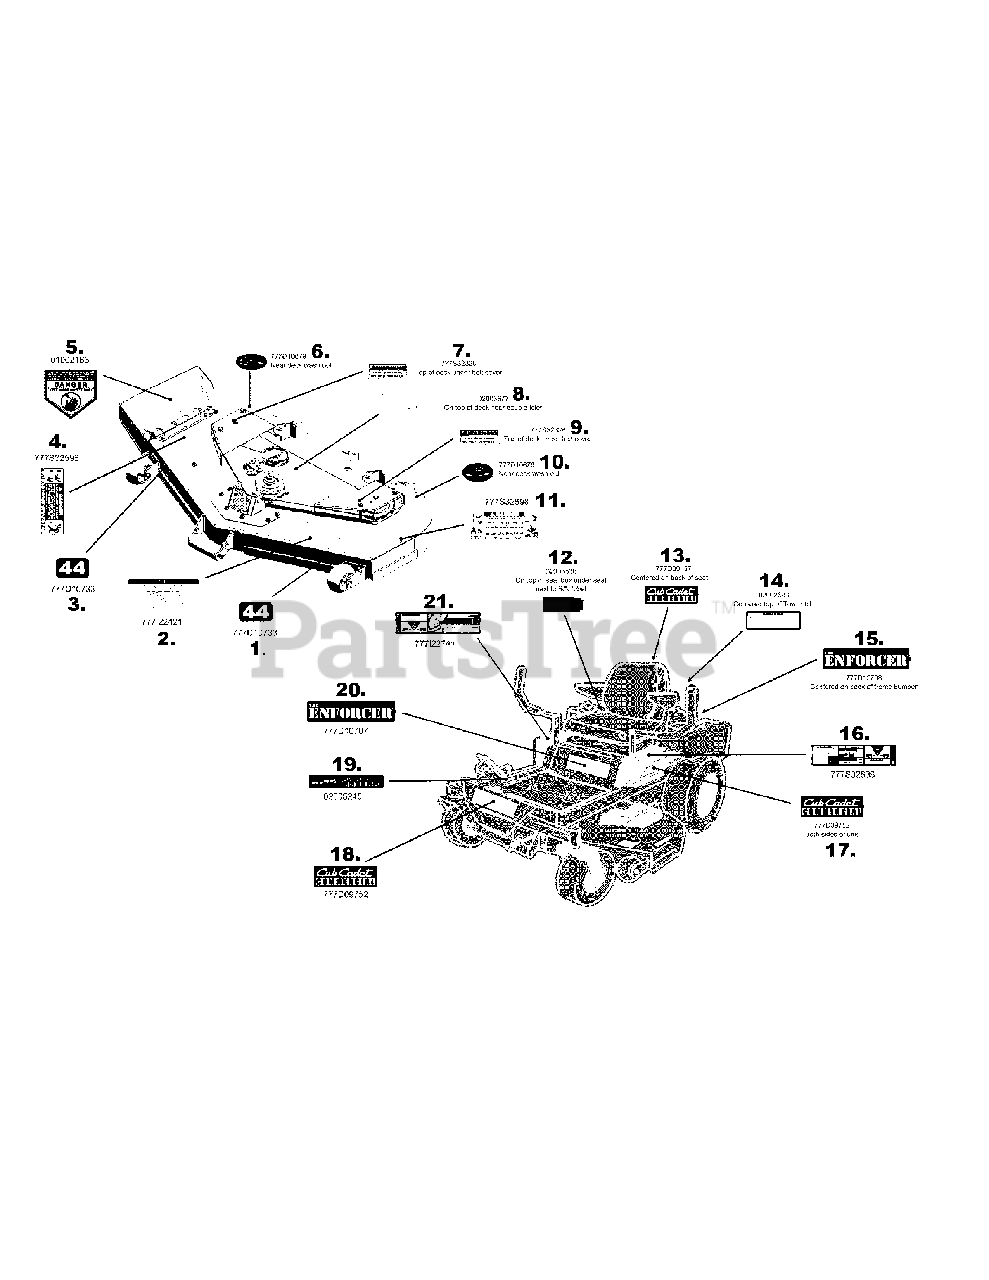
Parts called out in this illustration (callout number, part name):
1	LABEL-44" DECK
2	DECAL-44' DECK BELT RT Z-FORCE
3	LABEL-44" DECK
4	LABEL-RZT DECK WARNG STRAIGHT
5	LABEL-HANDS & FEET WALKBEHINDS
6	LABEL-DECK WASH
7	DECAL-WARNING
8	LABEL-DECK BELT ROUTE
9	DECAL-WARNING
10	LABEL-DECK WASH
11	LABEL-RZT DECK WARNG STRAIGHT
12	LABEL-PATENT
14	LABEL-WARNING TOW HITCH
15	LABEL-ENFORCER REAR BUMPER
16	LABEL-CONTROL
17	LABEL-CUB CADET COMM
18	LABEL-CUB CADET COMM
19	LABEL-DECK HEIGHT ADJ
20	LABEL-Z FORCE
21	LABEL-Z FORCE PANEL IGNIT
